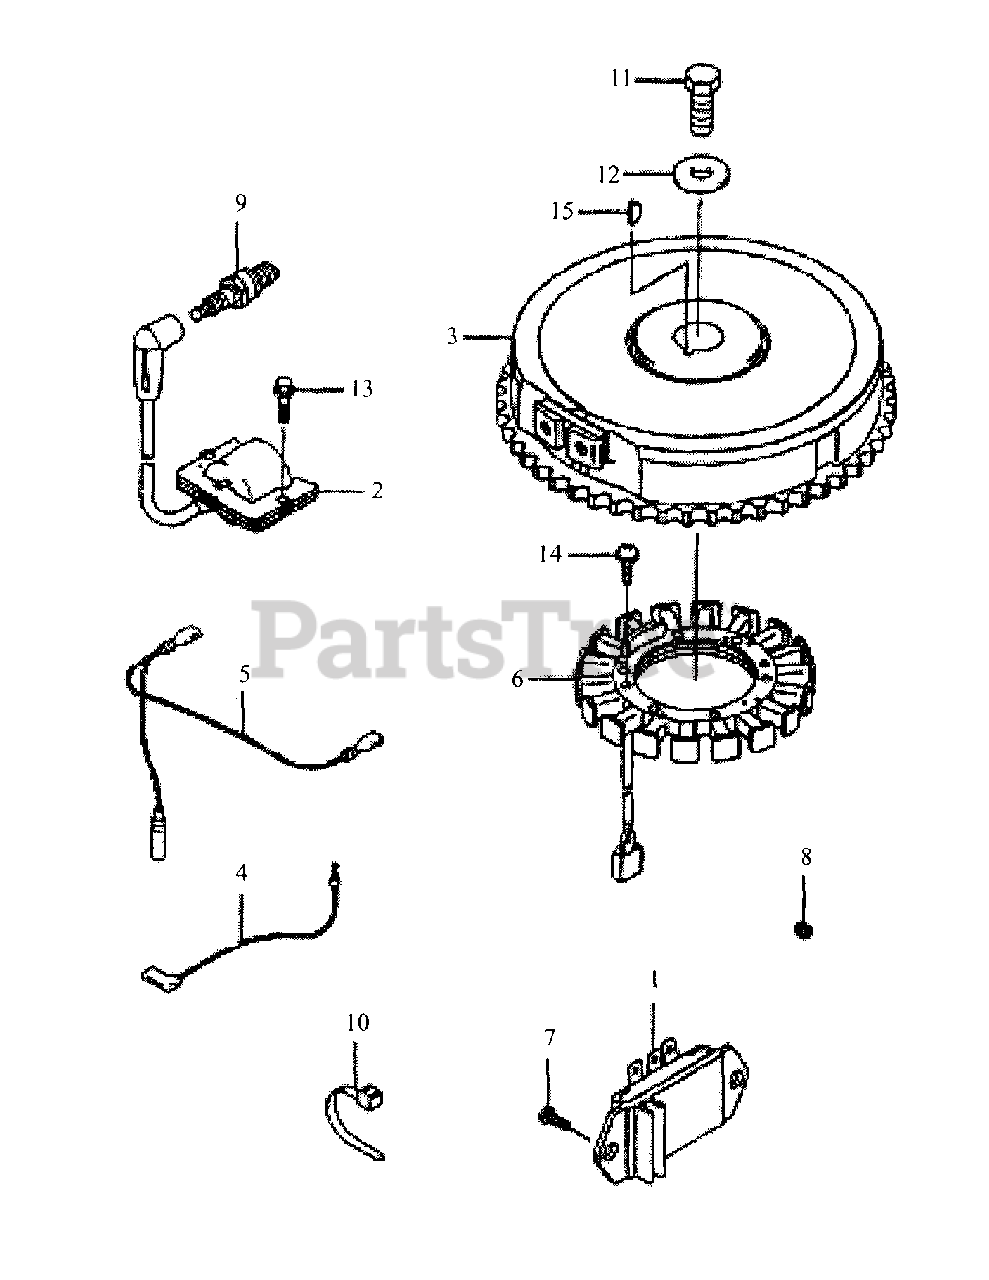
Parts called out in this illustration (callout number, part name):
1	Regulator, Voltage
2	Coil, Ignition
3	Flywheel
4	Wire, Lead
6	Coil, Charging
9	Spark Plug
11	Bolt 1200
13	Bolt, Flange
14	Screw Pan Hd.
15	Key-Woodruff
